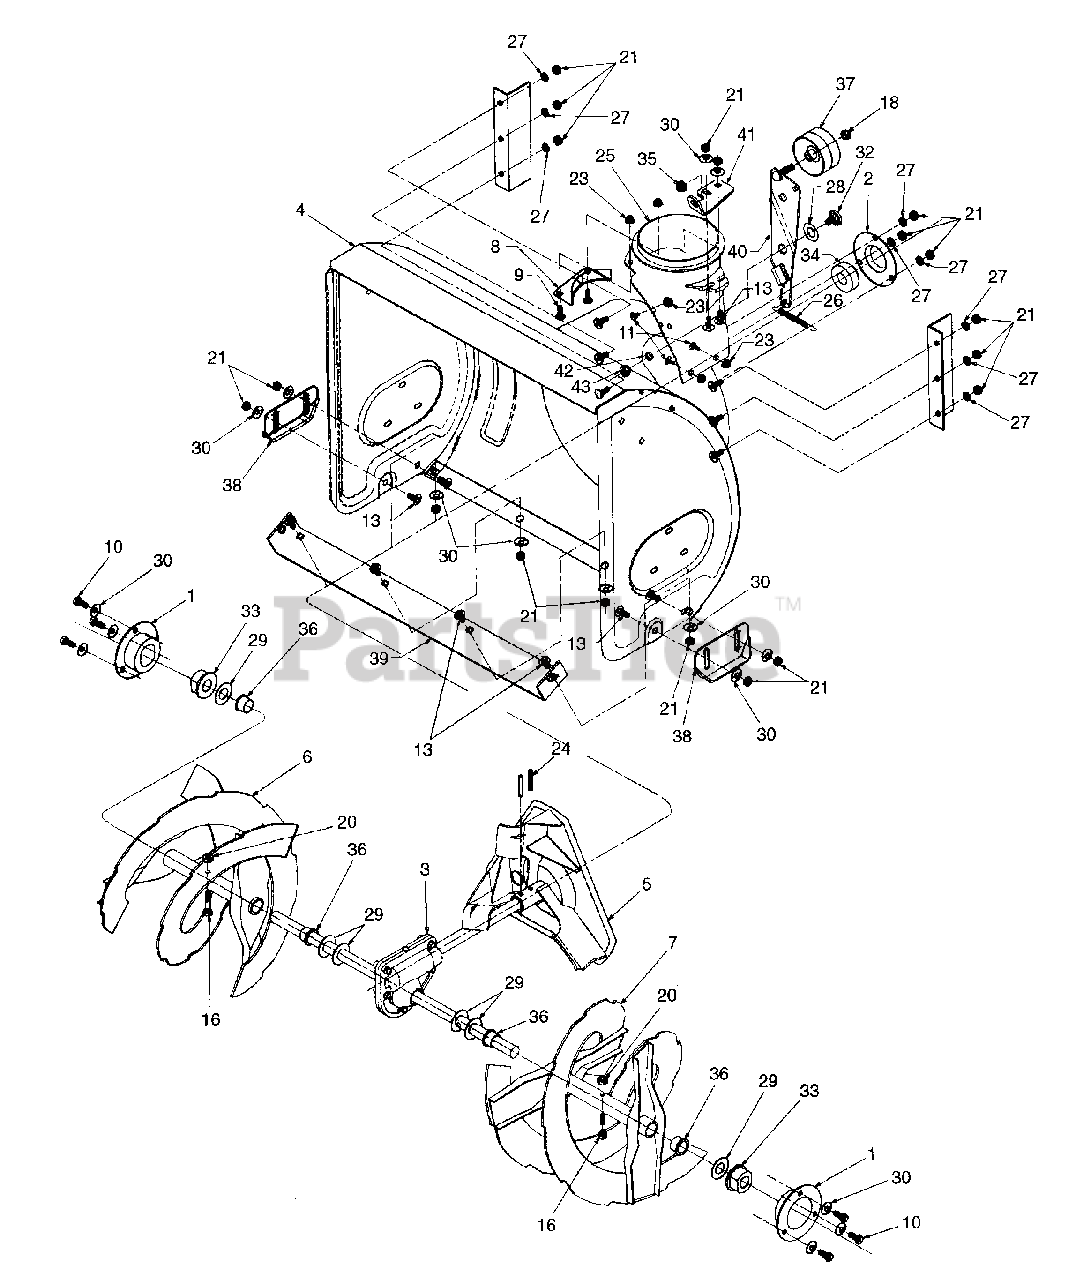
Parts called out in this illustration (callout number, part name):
2	Housing, Bearing
3	Gear Assembly (522E)
9	Bolt, Carriage, 1/4-20 x .50
10	Screw, Hex Wash Hd Tapp 5/16-18 x .62
11	Screw, Carriage, 1/4-20 x .50
13	Screw, Carriage, 5/16-18 x .75
16	Bolt, Shear, 5/16-18 x 1.5 (2 Spares)
18	Nut, Hex Insert Lock, 3/8-24
20	Nut, Hex Insert Lock, 5/16-18 (2 Spares)
21	Nut, Hex, 5/16-18
23	Nut, Hex Flange Lock, 1/4-20
24	Spring Pin, Spiral .25 x 1.5
25	Adapter, Chute
26	Spring, Extension
27	Lock Washer, 5/16
28	Washer, Flat, .65 x 1.25 x .02
29	Washer, Flat, .76 x 1.49 x .06
30	Washer, Bell, .345 x .88 x .06
32	Screw, Shoulder
33	Bearing, Flange, .75 ID
34	Bearing, Ball, .75 ID
35	Bushing, Plastic, .380 ID
36	Bushing, Flange, .80 ID x .91 OD
37	Idler, Flat
40	Arm, Auger Idler
42	Washer, Lock, 3/8
43	Nut, Hex 3/8-16
